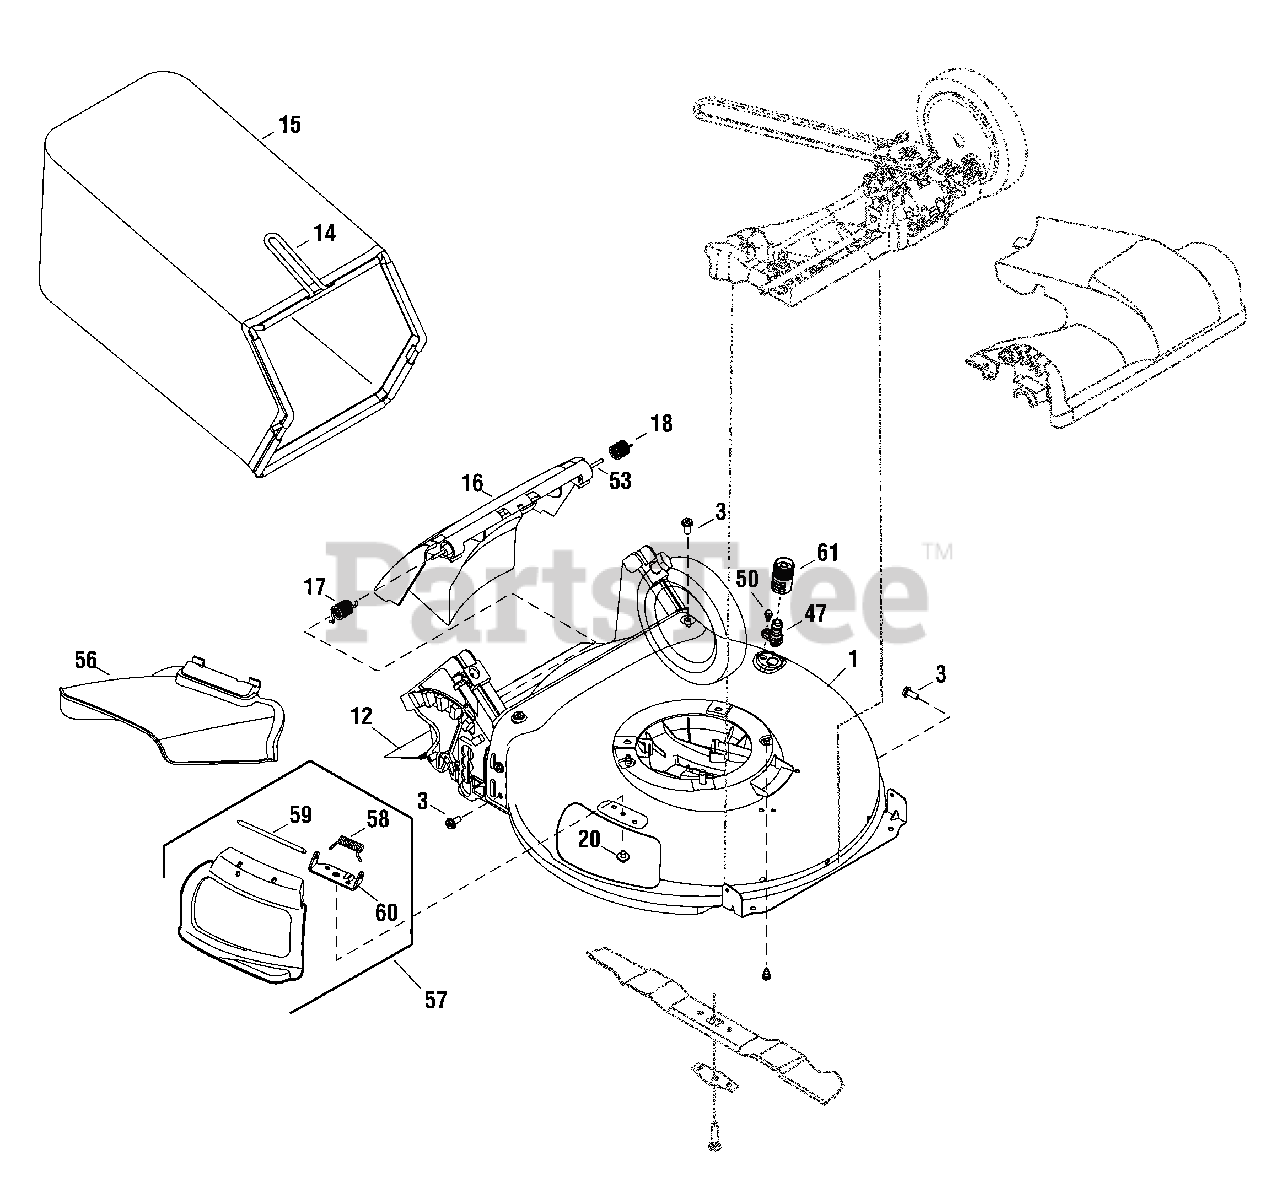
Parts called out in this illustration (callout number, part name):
3	SCREW, 5/16-14 x 3/4
12	SHIELD, Trailing
14	FRAME, Grass Bag
15	BAG, Grass
16	DOOR, Rear Discharge
17	SPRING, Torsion, RH
18	SPRING, Torsion, LH
20	SCREW, 1/4-20 x 1/2
47	NOZZLE, Water
50	BOLT, Shoulder, 1/4-20 x 1/2"
53	ROD, Pivot
56	CHUTE, Side Discharge
57	MULCH PLUG
58	SPRING, Torsion
59	PIN, Hinge
60	BRACKET, Chute Deflector
61	ADAPTER, Water Nozzle
